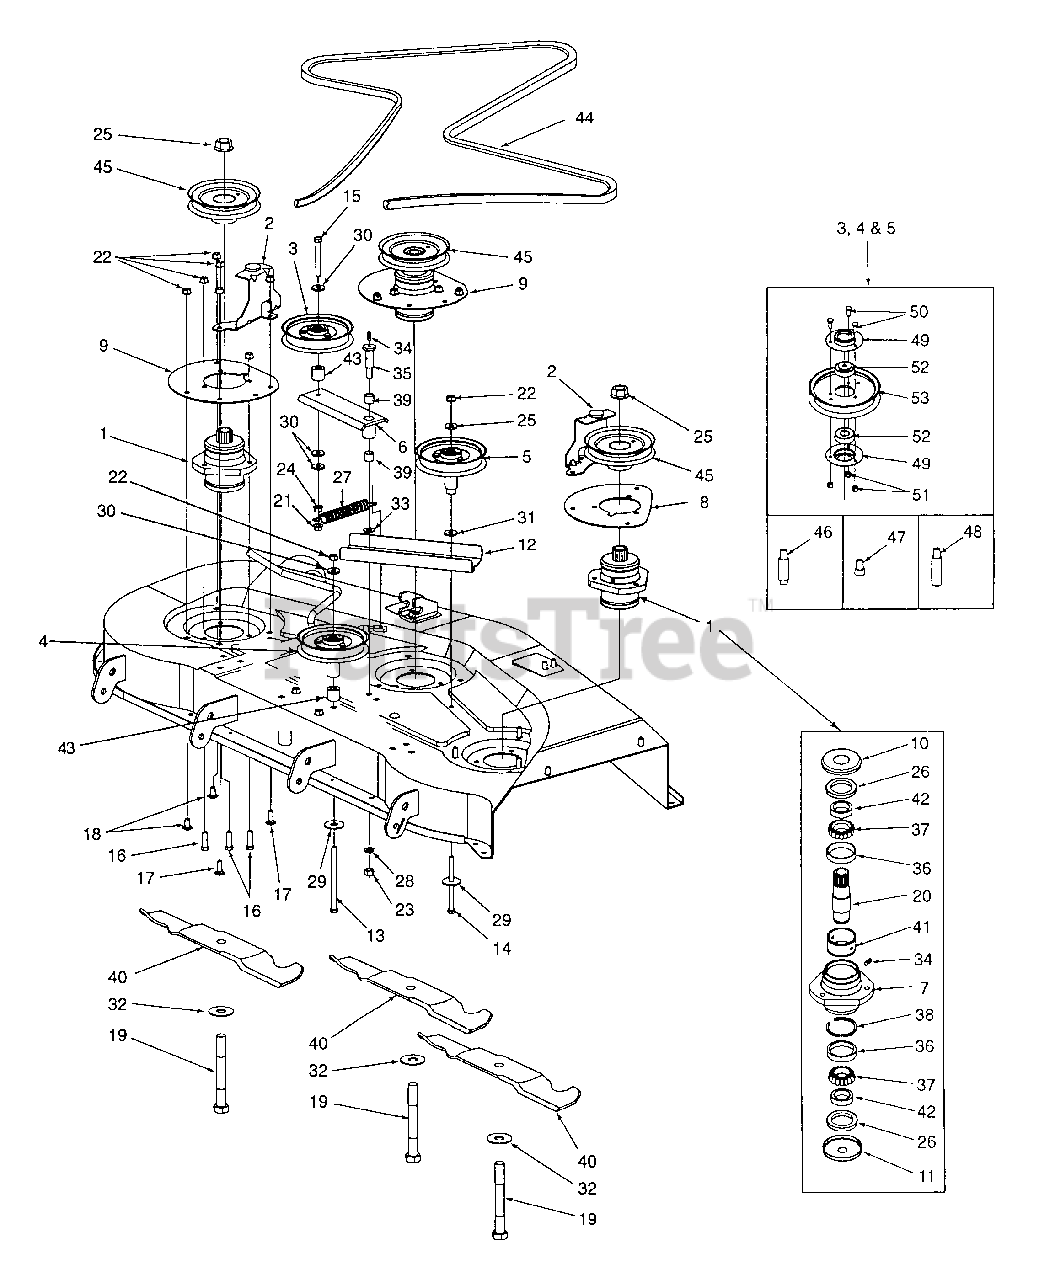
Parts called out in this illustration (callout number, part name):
1	Spindle Ass'y, Complete
4	Pulley Ass'y, 5" Idler
5	Pulley Ass'y, 5" Idler
14	Screw, Hex Cap, 3/8-16 x 4.5 GR5
15	Screw, Hex Cap, 3/8-24 x 3.75
16	Screw, Hex Cap, 3/8-16 x 1.25 GR5
17	Bolt, Carriage, 3/8-16 x 1.0 GR5
18	Bolt, Carriage, 3/8-16 x .75 GR5
19	Bolt, Hex Head, 3/4-16 x 6.0
20	Shaft, Spindle
21	Nut, Hex Center Lock Jam, 3/8-24
22	Nut, Hex Flange Lock, 3/8-16
23	Nut, Hex, 7/16-14
24	Nut, Hex Top Lock, 3/8-24
25	Nut, Hex Flange, 3/4-16
26	Oil Seal
27	Spring, Extension
28	Washer, Lock, 7/16
29	Washer, Flat, 3/8 x 1.5 x .134
30	Washer, Flat, .385 x 1.0 x .135
31	Washer, Flat
32	Washer, Flat, .78 x 2.0 x .105
33	Washer, Flat, .469 x .875 x .105
34	Fitting, Grease
35	Shoulder Bolt
36	Cup, Bearing
37	Bearing, Cone
38	Spacer, Bearing
39	Bearing, Sleeve
40	Mower Blade
41	Spacer, Bearing Cup
42	Ring, Seal
43	Spacer, .410 x 1.0 x .80
44	V-Belt, B Section 153.0 Lg
45	Pulley, Spindle
46	Spacer, Front Deck Idler Pulley
47	Spacer, Idler Arm Pulley
48	Spacer, Rear Deck Idler Pulley
49	Cup, Bearing
50	Screw, Hex Cap, 1/4-20 x .62 GR5
51	Nut, Hex Insert Lock, 1/4-20
52	Bearing, Ball
53	Pulley, Flat Idler
